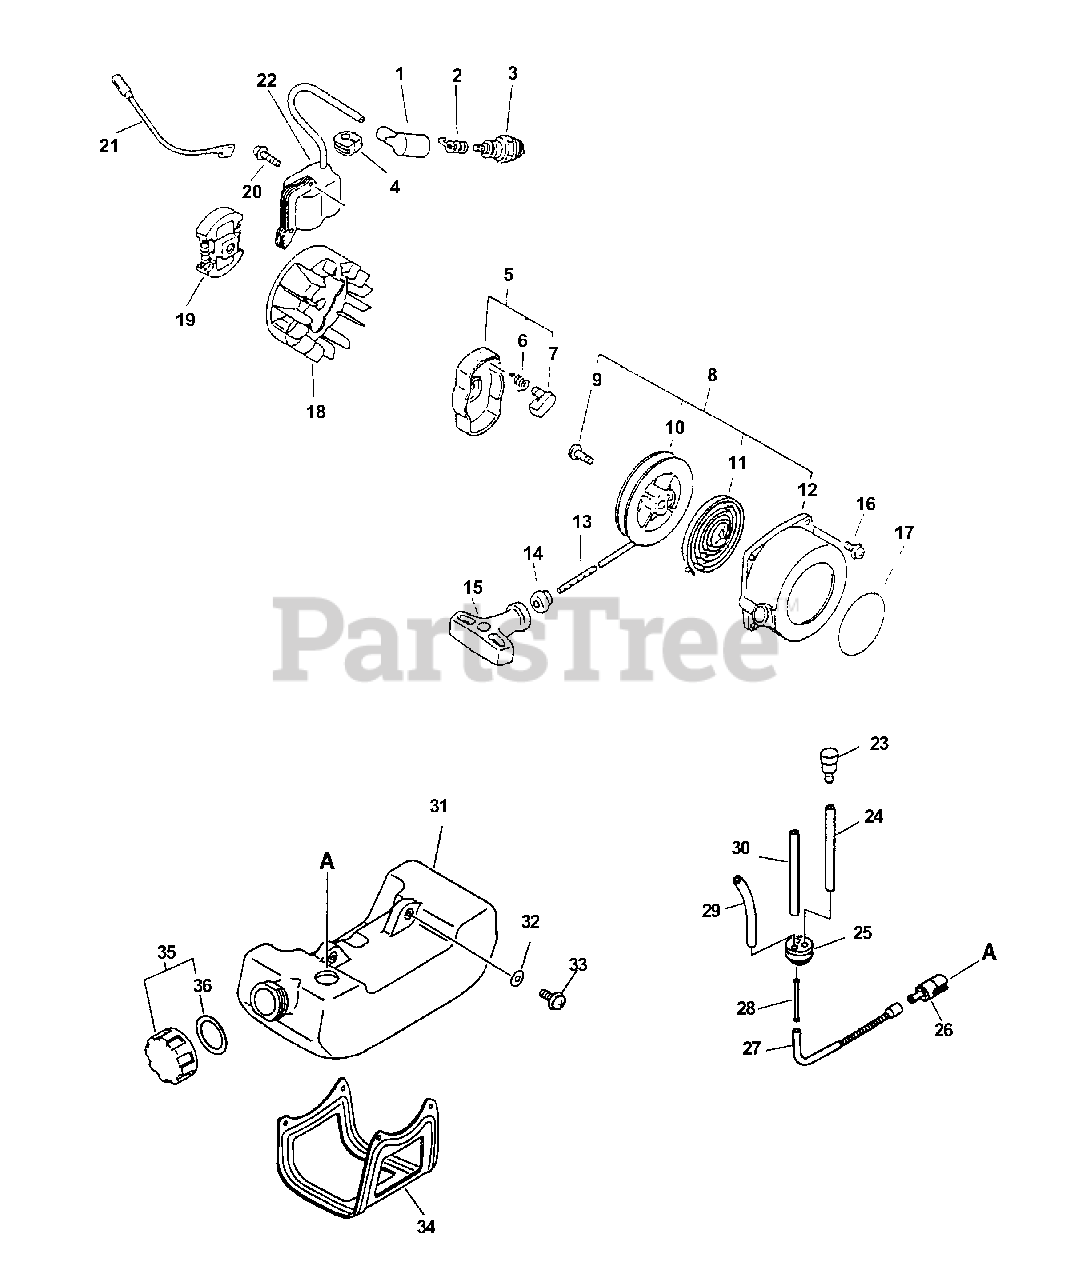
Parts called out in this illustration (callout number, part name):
1	CAP, SPARK PLUG
2	TERMINAL, SPARK PLUG CAP
3	SPARK PLUG -- BPM-7Y
3	SPARK PLUG -- RCJ-7Y
5	STARTER PAWL ASSY
6	SPRING, RETURN
7	PAWL, STARTER - BLACK
8	STARTER ASSY
10	REEL, ROPE
11	SPRING, REWIND
12	CASE, STARTER
13	ROPE, STARTER - 3X890
14	GUIDE, ROPE
15	GRIP, STARTER
16	SCREW - 4X16
17	LABEL - ECHO
18	FLYWHEEL
19	CLUTCH ASSY
20	SCREW - 4X22
21	LEAD - IGNITION
22	COIL, IGNITION
23	VENT, FUEL TANK
24	PIPE - 3X5X70 -- BLACK
25	GROMMET
26	FILTER, FUEL
27	PIPE, FUEL - CORRUGATED
28	CONNECTOR, PIPE
29	PIPE - 3X6X90 -- CLEAR
29	PIPE - 3X6X80 -- CLEAR
30	PIPE - 3X5X70 -- BLACK
31	FUEL TANK ASSY
32	WASHER - 5
33	SCREW - 5X16
34	GUARD, FUEL TANK
35	CAP ASSY
36	GASKET, CAP
